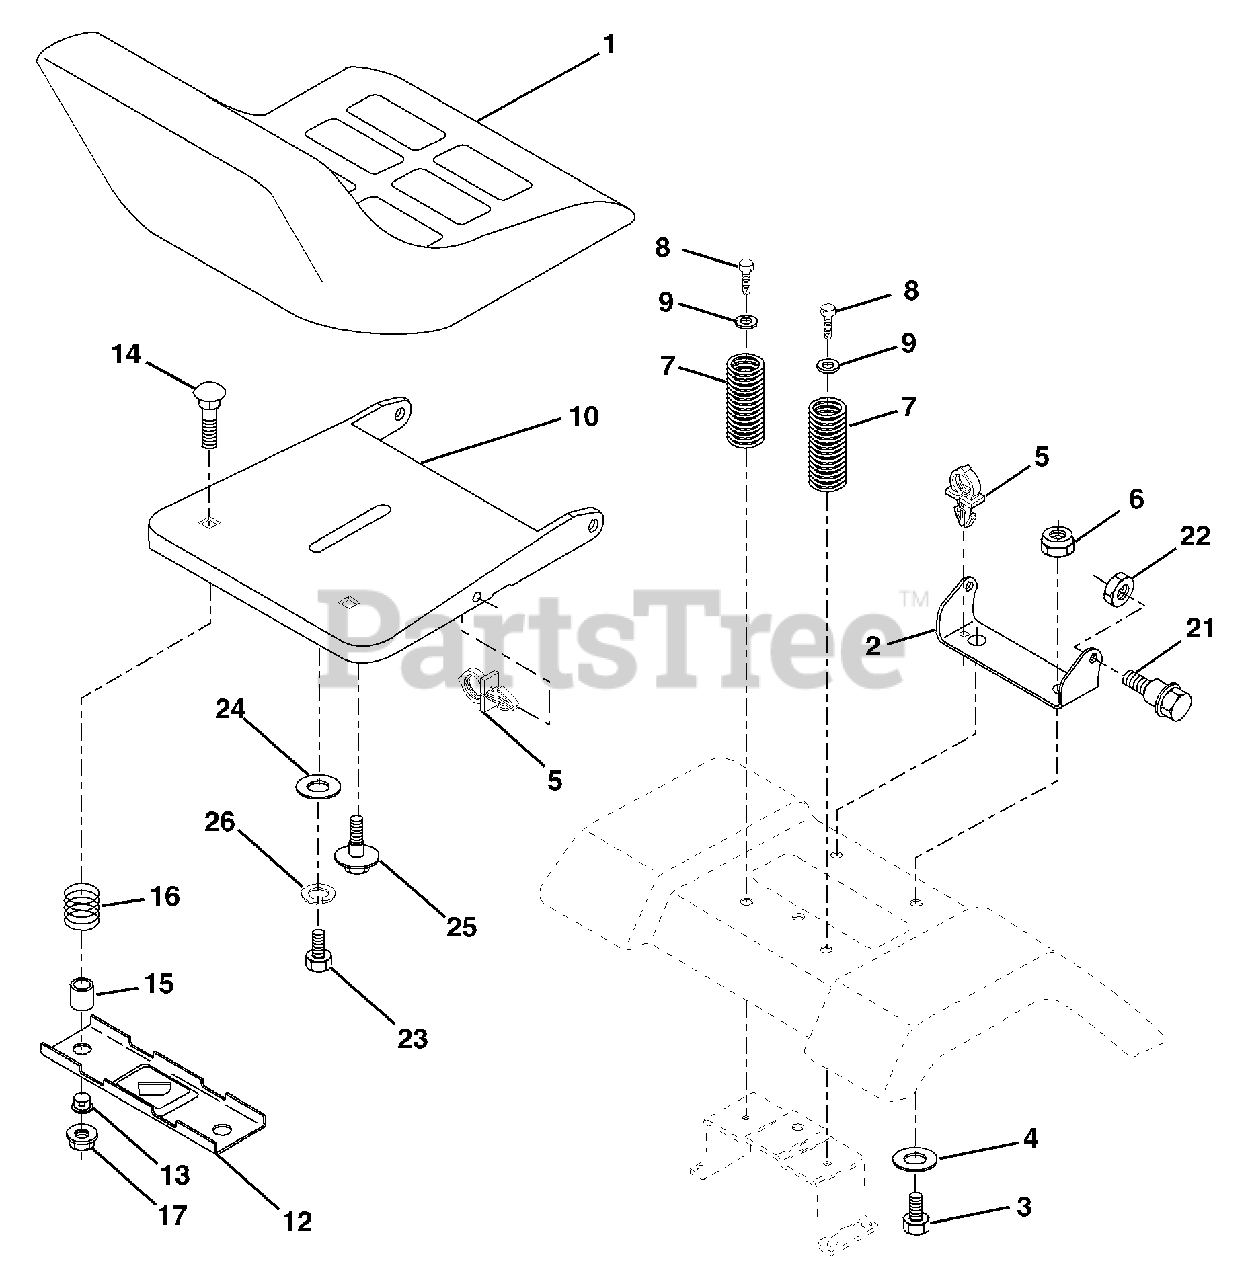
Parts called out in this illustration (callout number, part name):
1	Seat
2	Bracket Pnt Pivot Seat (blk)
3	Bolt
4	Washer 13/32 x 1 x 10 Ga
5	Clip Push-In Hinged
6	Nut
7	Spring Seat Cprsn 2 250 Blk Zi
8	Screw 3/8-16 x 1
9	Washer 13/32 x 1 x 14 Ga
10	Pan Pnt Seat
12	Bracket Pnt Mounting Switch
13	Bushing Snap Blk Nyl 50 Id
14	Bolt Rdhd Sht Nk 1/4-20 x 1-1/2
15	Spacer Split 28 x 96 Yel Zinc
16	Spring Cprsn 1 27 Blk Pnt
17	Nut Lock 1/4 Lge Flg Gr 5 Zinc
21	Bolt Shoulder 5/16-18 Unc Blkz-2A
22	Nut
23	Bolt Hex Black
24	Washer 17/32 x 1-3/16 x 12 Ga
25	Bolt Shoulder 5/16-18 x 62
26	Lockwasher
